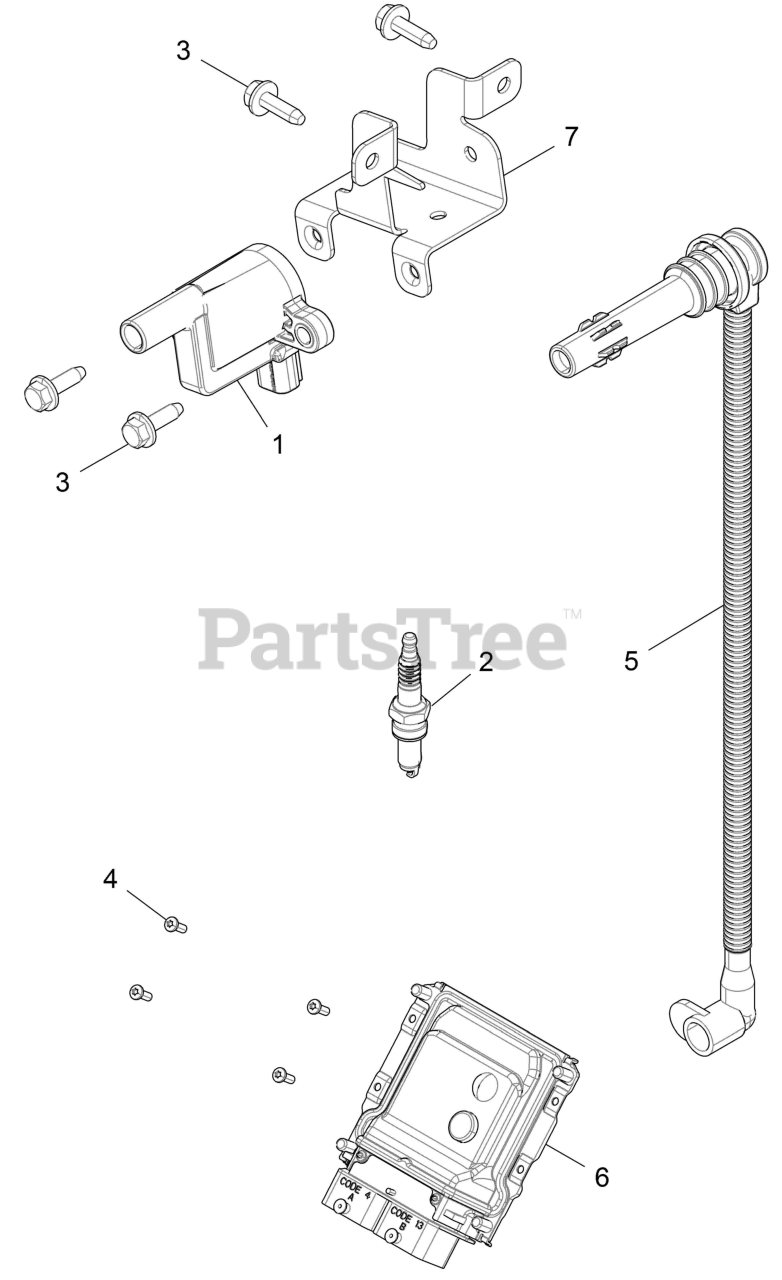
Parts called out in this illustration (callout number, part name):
1	COIL-IGNITION
2	SPARK PLUG-10 MM
3	SCR-M6X1.0X20,HXHD,FLG,TDFM,BL
4	SCR-#10X1/2-HI/LO-PN-T25,TRX-M
5	WIRE-SPARKPLUG,PTO
6	ECM-NO START,ME17
7	BRKT-AIRBOX MOUNT
